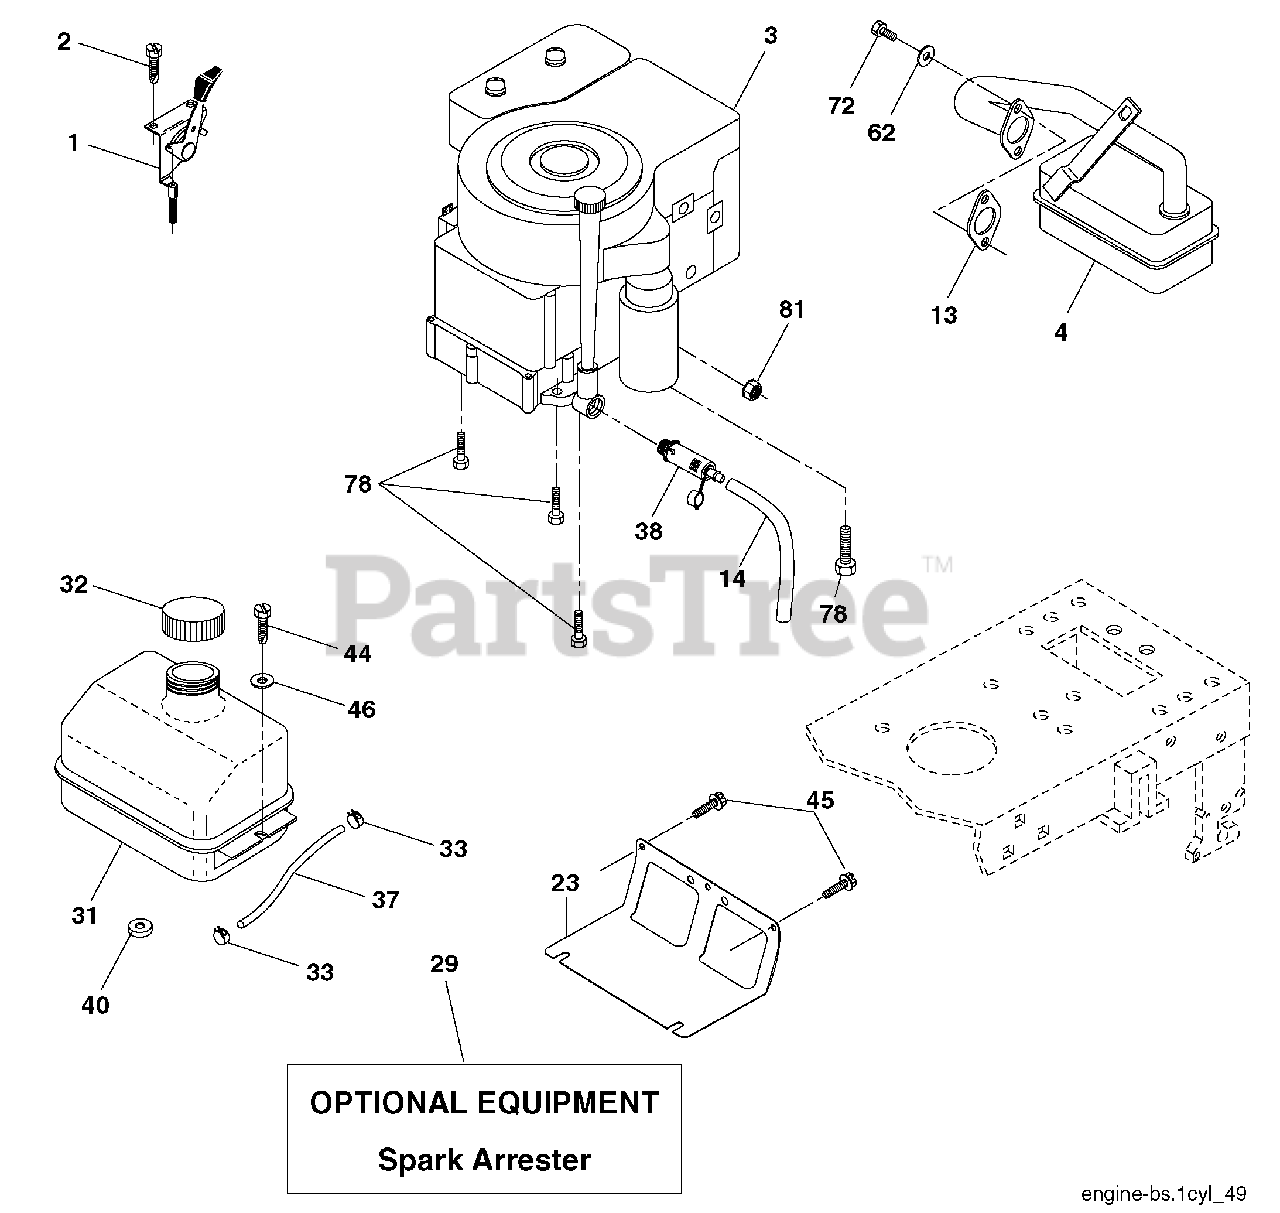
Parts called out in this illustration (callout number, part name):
1	Control, Throttle
2	Screw Hex Thd Cut 1/4-20 x 1/2
4	Muffl er
13	Muffl er Gasket
14	Tube Oil Drain
23	Shield, Browning/Debris Guard
29	Arrester, Spark
32	Cap, Fuel
33	Clamp, Hose Blk
37	Line, Fuel
38	Plug Drain Oil Easy
40	Bushing Snap
44	Screw Hex Wsh Thdrol 1/4-20 x 3/4
45	Screw Hex Wsh Thdrol 3/8-16 x 3/4
46	Washer 9/32 x 7/8 x 16 Ga.
62	Washer Split
72	Screw Hex Hd Cap 5/16-18 x 3/4
78	Screw 3/8-16 x 1-1/4
81	Nut Keps Hex 1/4-20 unc
